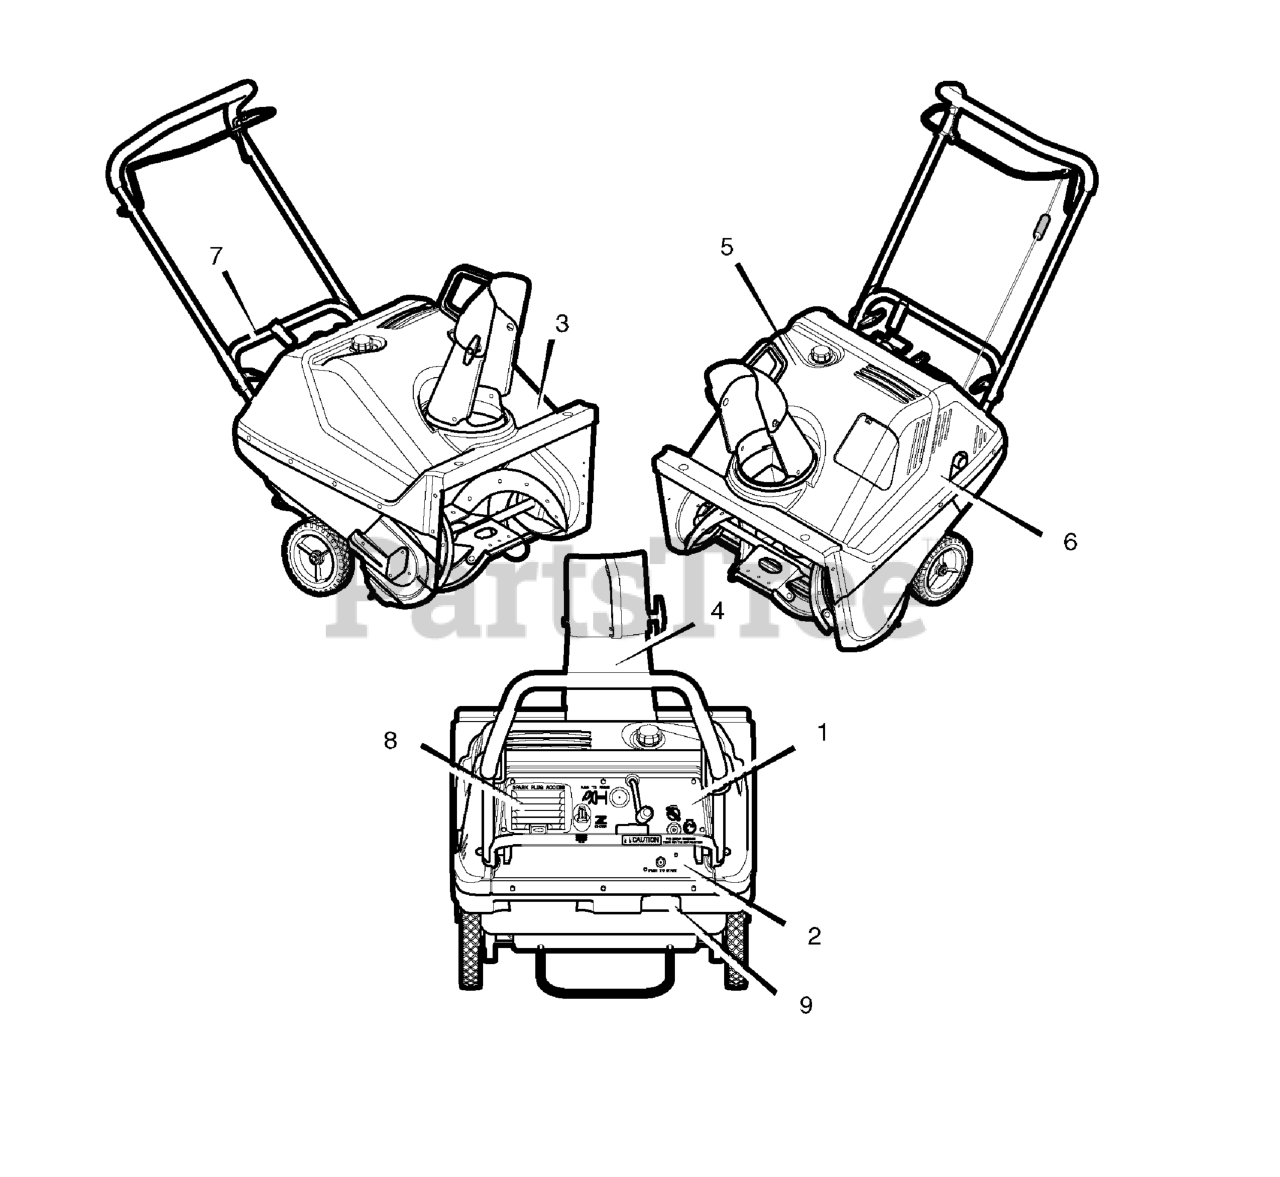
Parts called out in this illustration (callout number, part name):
1	Decal, Panel 22" ES SEARS
2	Decal, Electric Start
3	Decal, Auger Danger
4	Decal, Danger Chute Hand
5	Decal, CRAFTSMAN 22" 4-Cycle Start
6	Decal, Danger Muffler
7	Decal, Auger Control
8	Decal, Spark Plug Access 22"
9	Decal, Electric Plug Orientation
